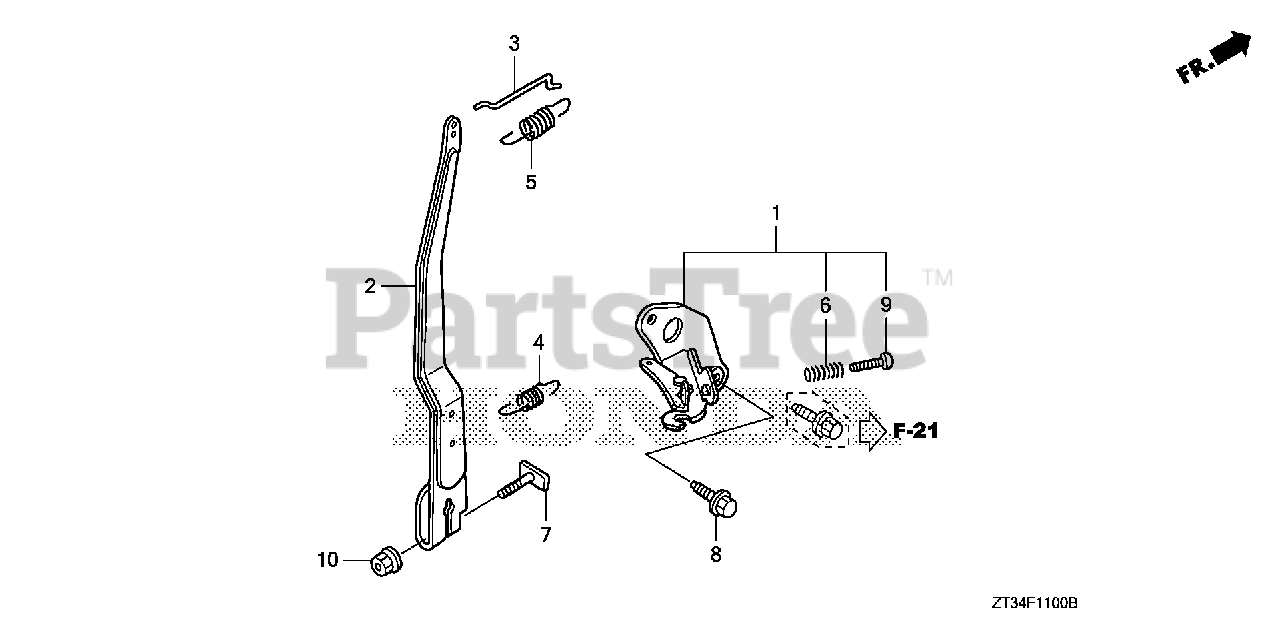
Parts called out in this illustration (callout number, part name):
1	CONTROL ASSY.
2	ARM, GOVERNOR
3	ROD, GOVERNOR
4	SPRING, GOVERNOR
5	SPRING, THROTTLE RETURN
6	SPRING, CONTROL ADJUSTING
7	BOLT, GOVERNOR ARM
8	BOLT, FLANGE (5X10)
9	SCREW, PAN (4X18)
10	NUT, FLANGE (6MM)
